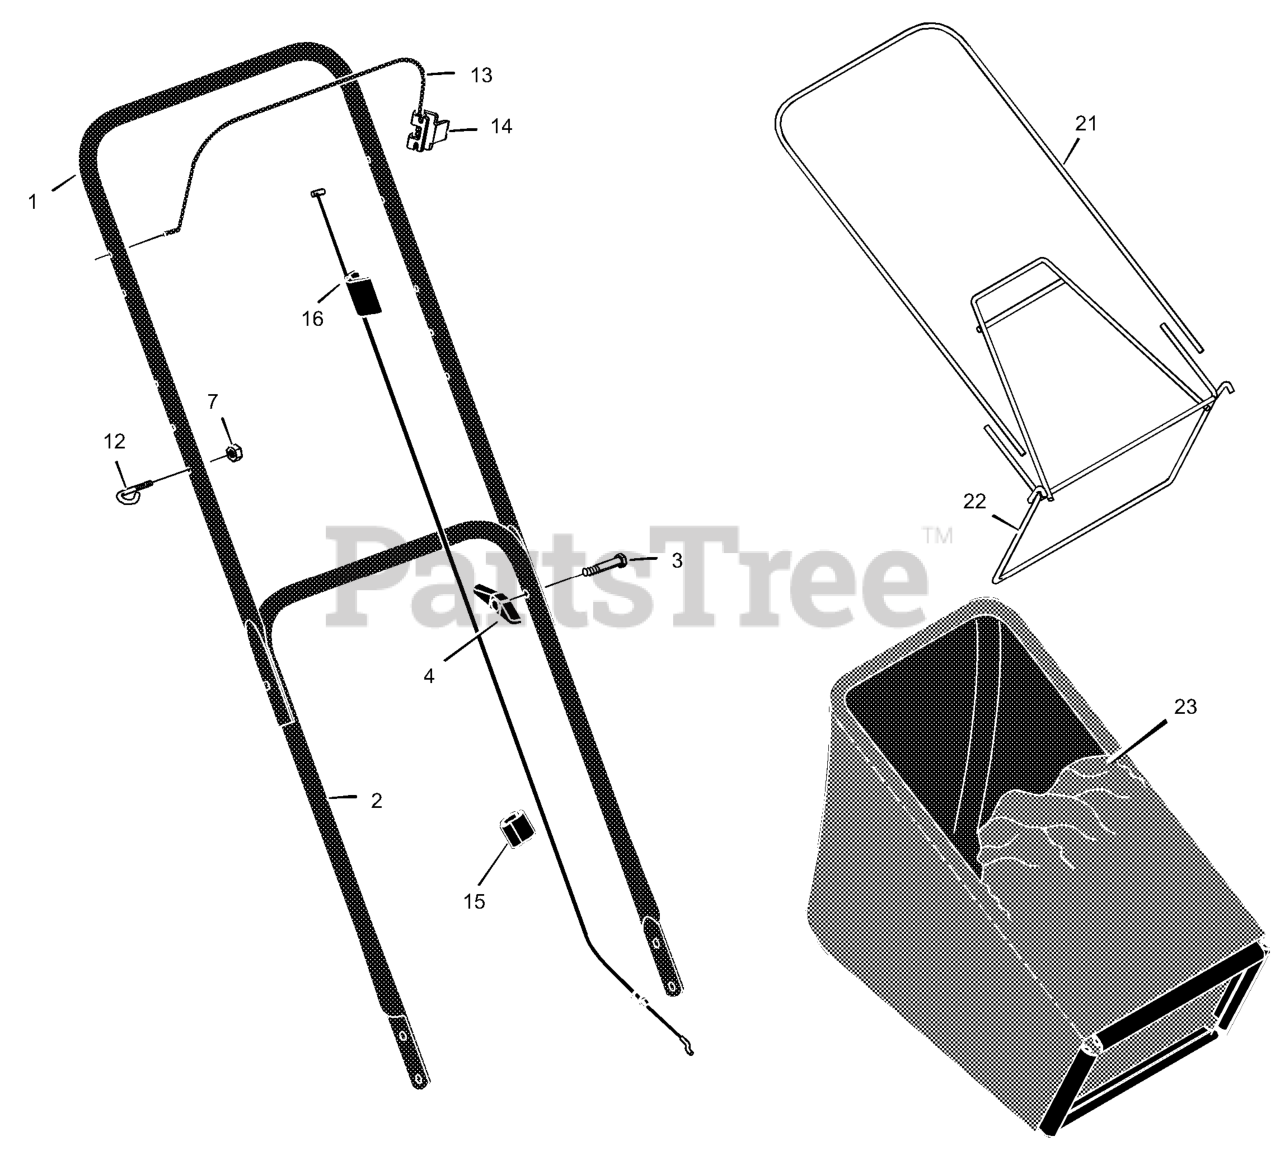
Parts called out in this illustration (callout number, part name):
1	Handle, Upper (Black)
2	Handle, Lower (Black)
4	Knob, Plastic
7	Locknut
12	Guide, Rope
13	Engine Stop Lever
14	Bracket, Stop Lever
15	Fastener, Cable
16	Engine Stop Cable
21	Frame, Top
22	Frame Assembly
23	Bag, Cloth
